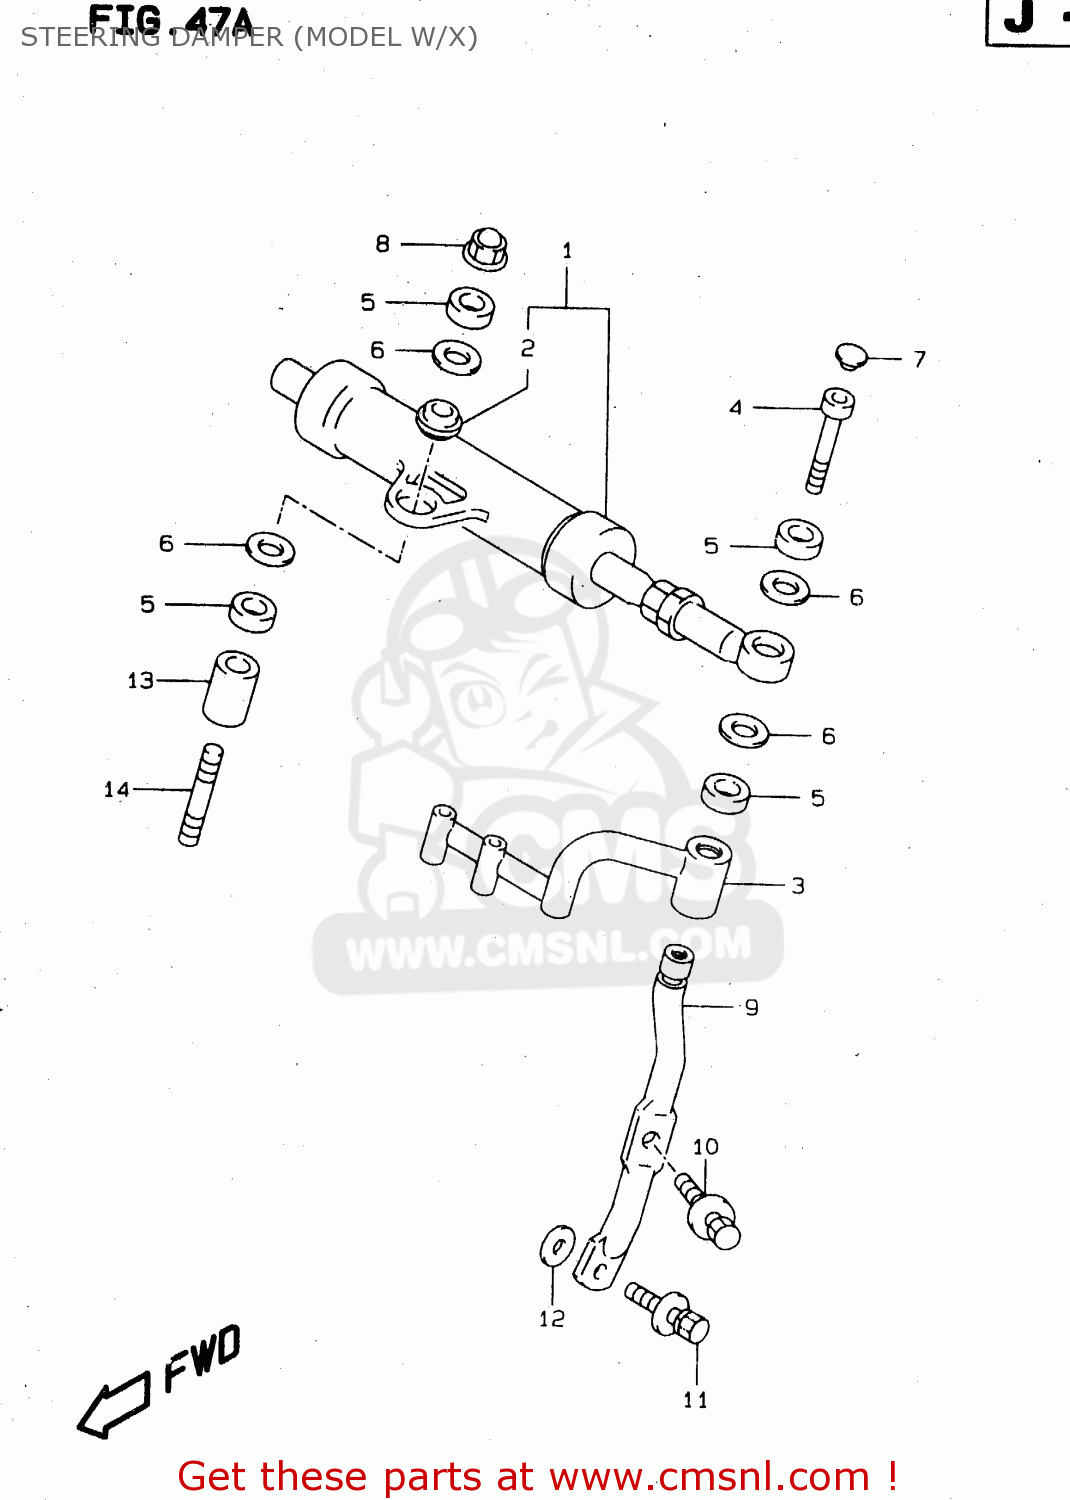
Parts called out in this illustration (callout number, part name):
1	DAMPER ASSY, STEERING
2	BEARING(8X17.5X11)
3	STAY,STEERING DAMPER
4	BOLT
5	6
6	SHIM(8X12X0.8)
7	CAP(OD:11)
8	NUT
9	ROD,STEERING DAMPER
10	BOLT(6X30)
11	BOLT,STAY,LOWER 6X35
12	WASHER(6.5X20X1.6)
13	SPACER,STEERING DAMPER
14	BOLT,STUD(8X50)
